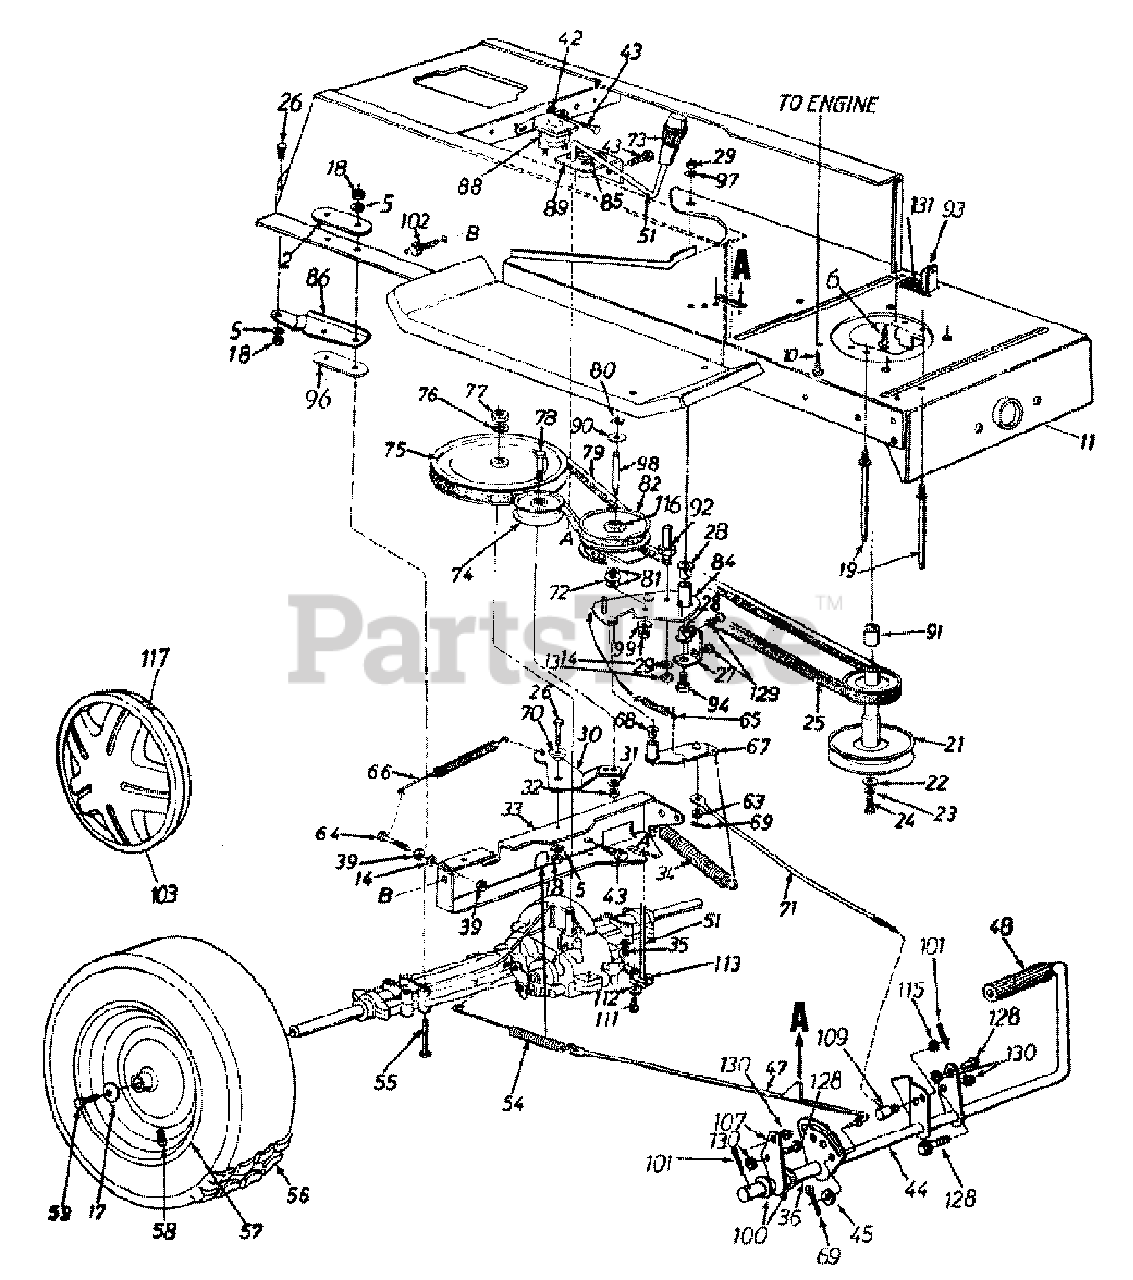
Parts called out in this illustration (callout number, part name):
5	L-Wash. 5/16" I.D.
10	Hex TT-Tap Scr. 3/8-16 x 1.5" Lg.
13	Hex Nut 1/4-20 Thd. (Gr. 5)
14	L-Wash. 1/4" I.D.
17	Bell-Wash. .345" I.D. x .88"
18	Hex Nut 5/16-18 Thd. (Gr. 5)
19	Belt Guard Stud 4.75" Lg.
21	Engine Pulley
22	Fl-Wash. 7/16" I.D. x 1.25"
23	L-Wash. 7/16" I.D.
24	Hex Bolt 7/16-20 x 1.25" Lg.
25	Variable-Speed Belt
26	Hex Bolt 5/16-18 x .75" Lg.
27	Bearing Shaft Bracket Ass'y.
28	Flanged Nyliner Brg. 5/8" I.D. x .88" Lg.
29	Hex Nut 3/8-24 Thd.
31	L-Wash. 3/8" I.D.
32	Hex Nut 3/8-24 Thd.
35	Inter. Cotter Pin
36	Spacer .63" I.D.
39	Hex Nut 1/4-28 Thd.
42	Ext. L-Wash. 1/4" I.D.
43	Hex Wash. Hd. S-Tap Scr. 1/4-20 x .50" Lg.
47	Brake Rod Ass'y.
48	Foot Pad
51	Shift Lever Ass'y.
54	Ext. Spring .59" O.D. x 7.08"
55	Hex Bolt 5/16-18 x 3.5" Lg.
58	Air Valve
59	Hex Bolt 5/16-24 x .75" Lg.
63	Fl-Wash. .34" I.D. x .68" O.D.
64	Hex Bolt 1/4-28 x 1.25" Lg.
65	Ext. Spring
66	Ext. Spring .62" O.D. x 6.12"
68	Flanged Bearing
69	Cotter Pin 3/32" Dia.
70	Shoulder Spacer .27" Lg.
71	Speed Control Link
72	Truss Bearing .56 Dia. x 1.25"
73	Shift Knob
74	Fl-Idler Pulley 3.12" Dia.
75	"V" Pulley
76	Bell-Wash. .56" I.D. x 1.125"
77	Hex Jam Nut 5/16-18 Thd.
78	Hex Bolt 3/8-24 x 1.75" Lg.
79	Variable Speed Belt
80	Snap Ring .56" Dia.
82	Variable Speed Pulley Ass'y. 5" O.D.
90	Teflon Washer .565" I.D.
91	Spacer 1" I.D. x 1.25" Lg.
92	Belt Keeper 3" Lg.
93	Safety Switch (Clutch)
94	Shld. Bolt 3/8-24 x 3.12" Lg.
97	Bell-Wash. .38" I.D. x .88"
98	Shaft .56" Dia. x 3.875" Lg.
99	Bell-Wash. .39" I.D. x 1.12"
100	Fl-Wash. .64" I.D. x .94"
101	Cotter Pin 1/8" Dia. x 1.25"
102	Hex Wash. Hd. Scr. 5/16-18 x .62" Lg.
103	Hub Cap (Gray-Optional)
111	Hex Bolt 1/4-28 x .50" Lg.
112	Bell-Wash. .265" I.D. x .75"
113	Shift Lever Link Ass'y.
115	Fl-Wash. .385" I.D. x .62"
116	Needle Brgs.
117	Spring Clip
128	Hex Wash. TT-Tap Scr. 5/16-18x .75" Lg.
129	Hex Wash. AB-Tap Scr. 5/16-18x .75" Lg.
130	Hex Sems Nut 5/16-18 Thd.
131	Spring Switch
